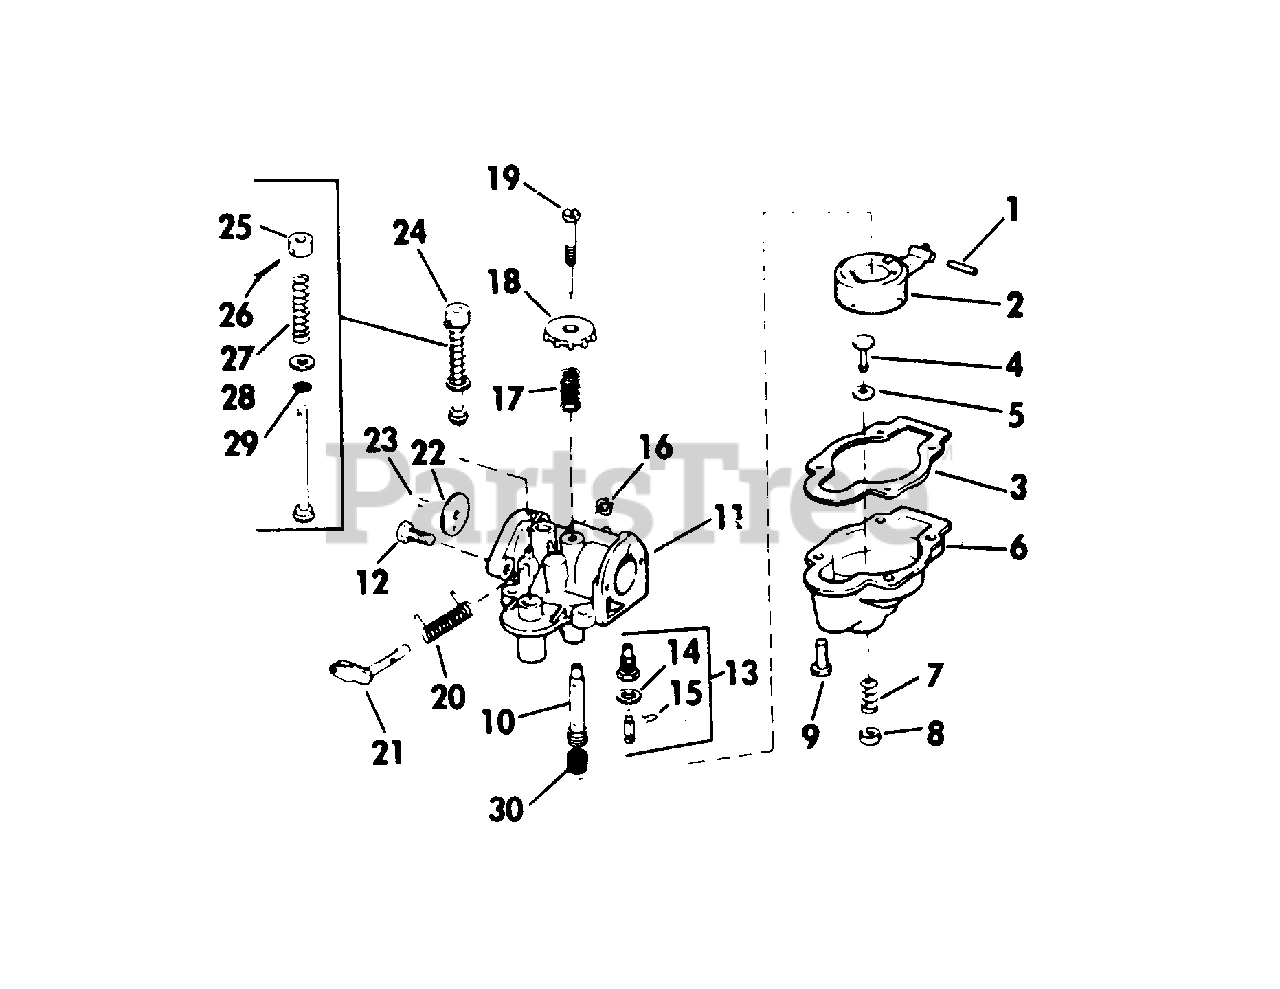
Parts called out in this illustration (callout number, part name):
1	Pin-Float Arm Hinge
2	Float and Arm Assy.
3	Gasket-Float Chamber
4	Valve Stem
5	Valve Seat
6	Chamber-Float
7	Valve Spring
8	Valve Keeper
9	Screw-Float Chamber
10	Nozzle
11	Carburetor Body Assy.
13	Float Valve & Seat
14	Washer-Float Valve Seat
15	Clip
16	Grip Ring
17	Spring-Needle Adj.
18	Knob-Needle Adj.
19	Needle Assy.
20	Spring-Throttle
21	Throttle Shaft & Lever Assy.
22	Disc-Throttle
23	Screw-Throttle Shaft Disc
24	Primer Assy.
25	Knob Primer
26	Cotter Pin
27	Spring Compression
28	Washer-Plain
29	"O" Ring
